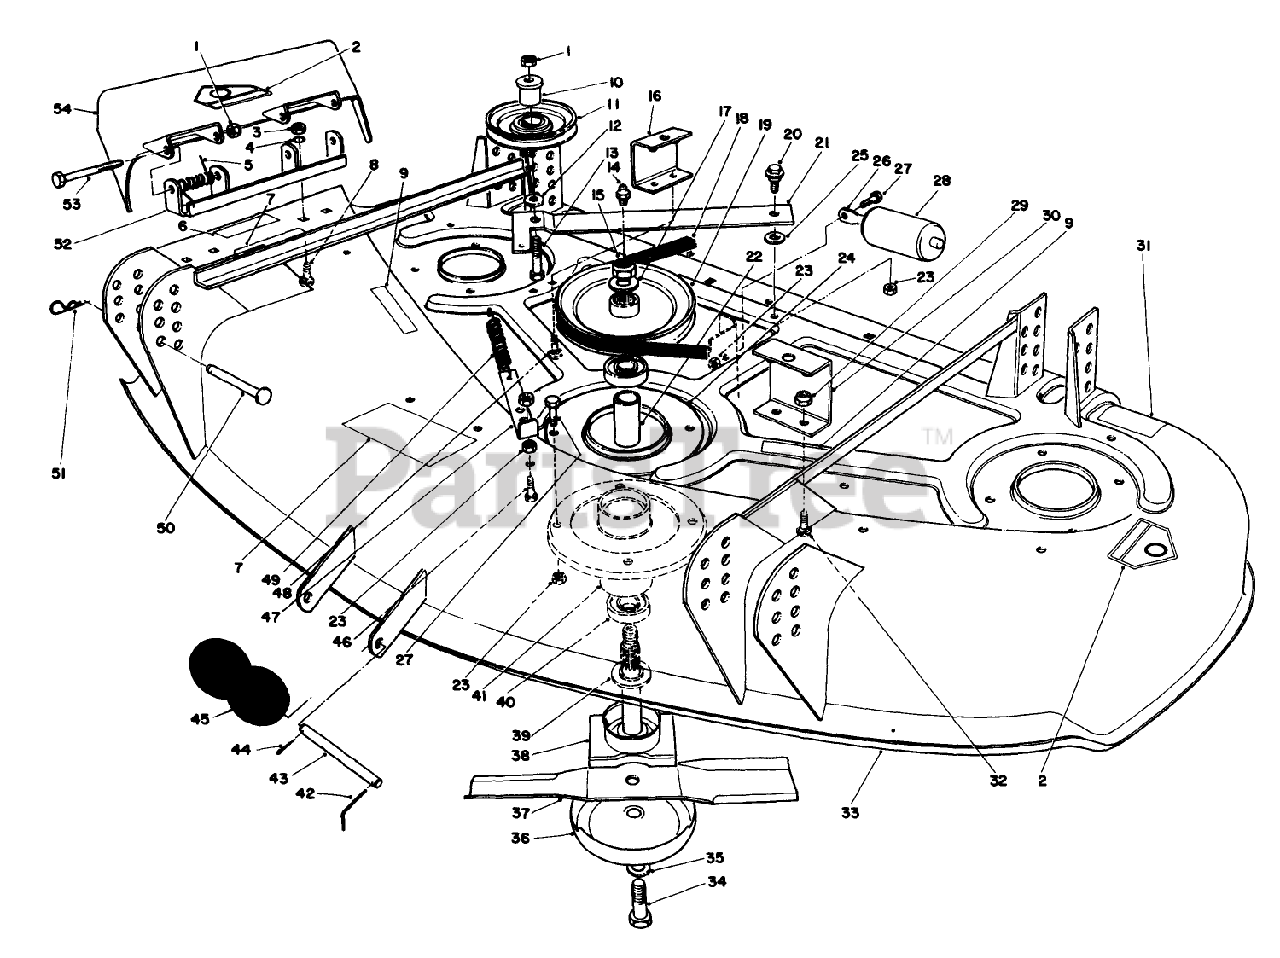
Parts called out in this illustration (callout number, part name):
1	NUT-HEX
2	DECAL-DANGER
3	NUT-HEX
4	WASHER-LOCK
5	SPRING
6	DECAL-DANGER
7	DECAL-DANGER, THROWN OBJECT
8	SCREW-CARR
9	DECAL-DANGER
10	BUSHING-PULLEY
11	PULLEY-IDLER
12	WASHER-FLAT
13	SCREW-HH
14	FITTING-GREASE
15	NUT-HEX
16	Bracket-Cover RH
17	WASHER
18	V-BELT-DECK
19	PULLEY-DECK
20	SCREW-SHOULDER
21	Lever-Deck
22	SPACER-BEARING
23	NUT-LOCK, CONE
24	DECK RING
25	WASHER
26	ROD-ROLLER
27	SCREW-HH
28	ROLLER-DECK
29	NUT-LOCK, NI
30	Bracket-Cover LH
31	DECAL-TORQUE
32	SCREW-CARR
33	44" Deck Assembly (Incl. Ref. #2, 6,7, 9 & 31)
34	SCREW-BLADE
35	WASHER-LOCK
36	Anti-Scalp Cup
37	Blade
38	SHAFT-SPINDLE
39	SPACER-SPINDLE
40	BEARING-BALL
41	HOUSING-SPINDLE
42	PIN-SPECIAL
43	SHAFT-ROLLER
44	PIN-COTTER
45	ROLLER
46	SCREW-HH
47	Anchor-Deck Spring
48	SCREW-CARR
49	SPRING-EXTENSION, DECK
50	PIN-CLEVIS
51	PIN-HAIR
52	PIVOT BRKT WA R/B
53	SCREW-HH
54	DEFLECTOR
